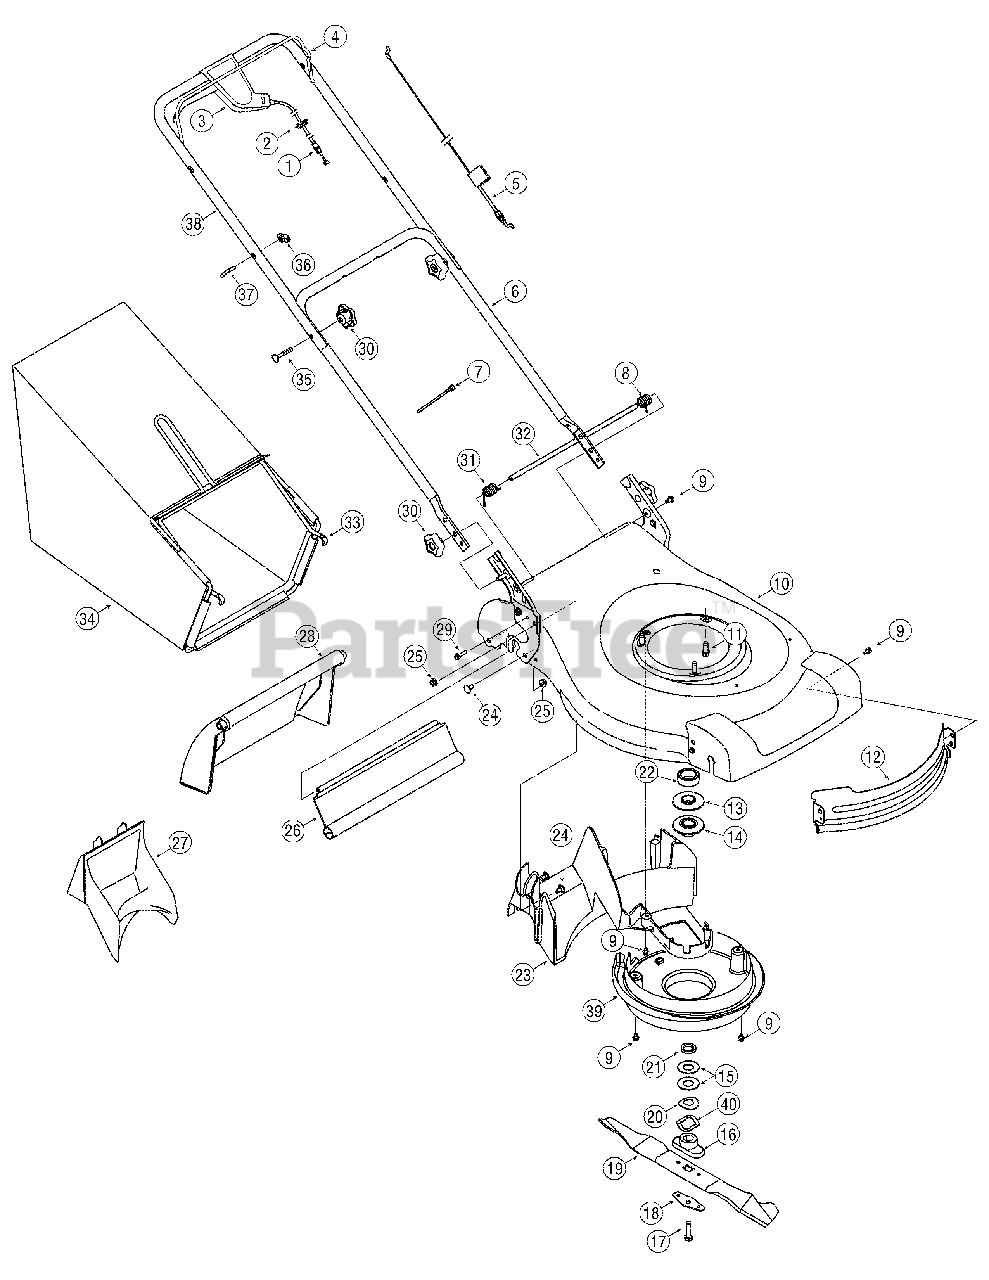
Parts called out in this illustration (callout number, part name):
1	Drive Cable
2	Rubber Grommet
3	Drive Control Assembly
5	Control Cable
7	Cable Tie
8	Torsion Spring, LH
9	TT Screw, 1/4-20 x .62
10	21-inch Deck
11	TT Screw, 3/8-16 x 1.00
12	Deck Baffle
13	Upper Engine Pulley
14	Lower Engine Pulley
15	Flat Washer, .885 x 1.850 x .060
16	Blade Adapter
17	Screw, 3/8-24 x 1.50
18	Blade Bell Support
19	21" Mulching Blade
20	Sprg Washer, .890 x 1.70 x .048
21	Sleeve Spacer
21	Slv. Spcr., 25mm x 1.375 x .375
22	Sleeve Spacer
23	Deck Baffle
24	Carriage Bolt, 5/16-18 x .62
24	Hex Cap Screw, 5/16-18 x .625 GR5
25	Flange Lock Nut, 5/16-18
26	Trailshield
27	Mulch Plug
28	Rear Door
29	Screw, 1/4-15 x 1.00
30	Star Knob
31	Torsion Spring, RH
32	Door Pivot Rod
35	Carriage Bolt, 5/16-18 x 2.00
36	Wing Nut
37	Eye Bolt
40	Washer, Wave, 1.5 x 1.0 x .029
